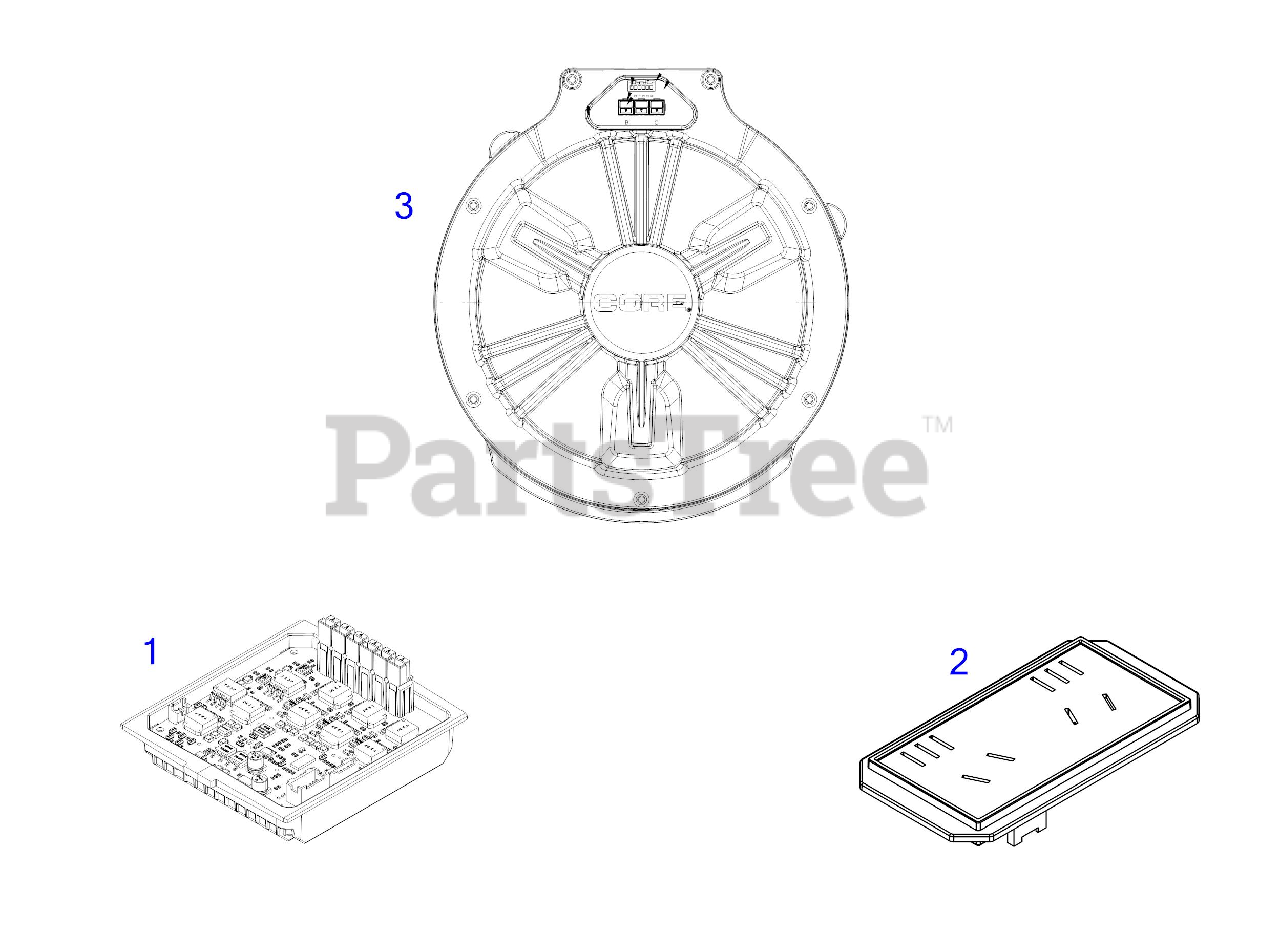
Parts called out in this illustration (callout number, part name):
1	CONTROLLER ASSEMBLY
2	MOWER PANEL
3	CORE MOTOR ASSEMBLY
